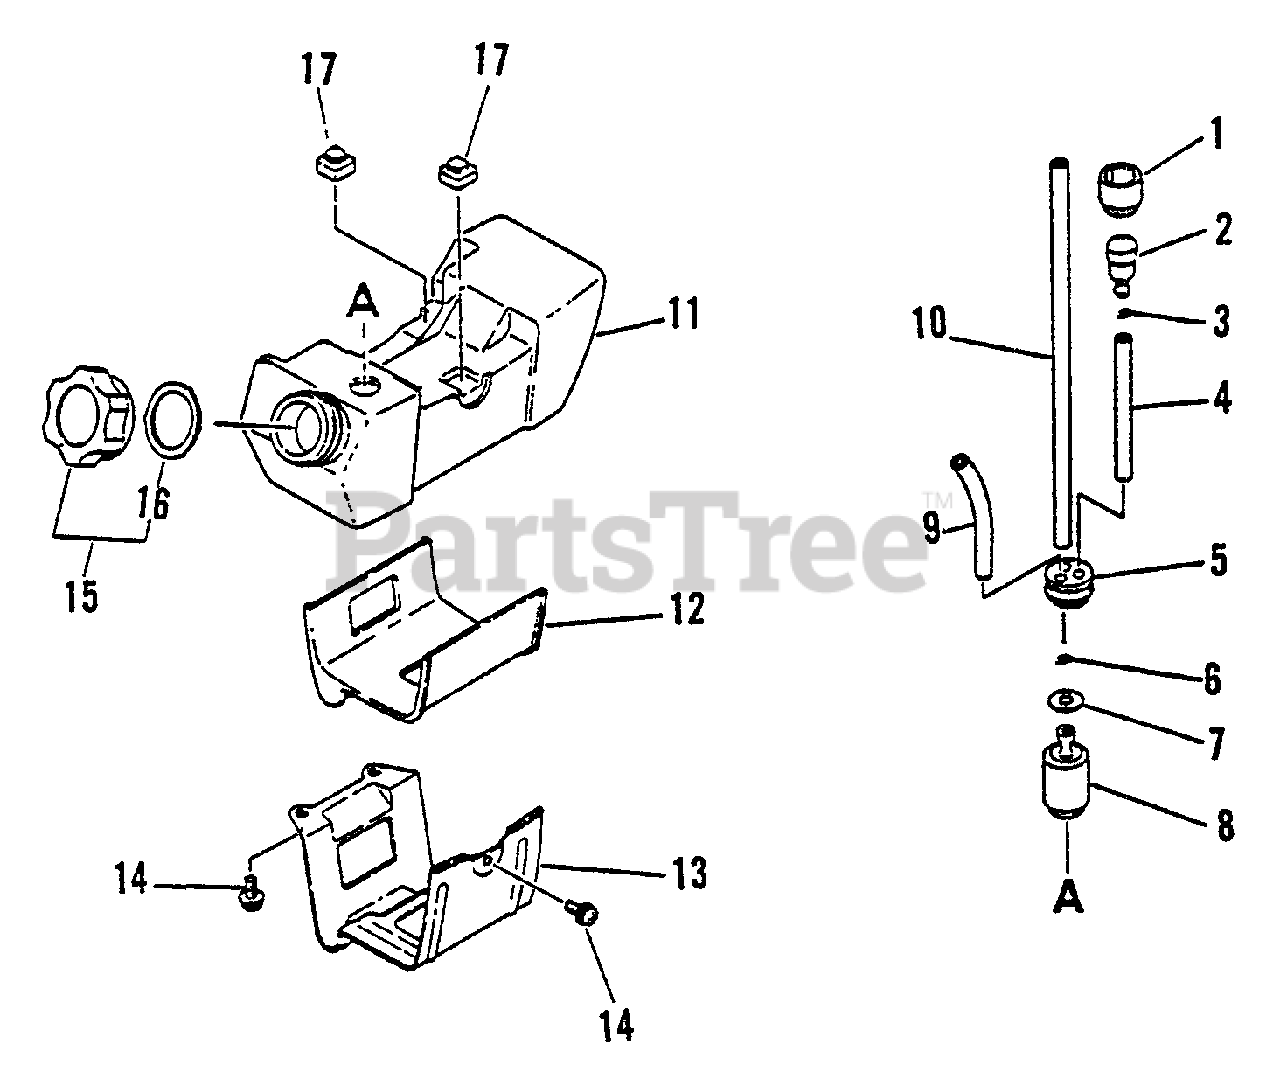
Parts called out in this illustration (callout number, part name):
1	COVER, VENT
2	VENT, FUEL TANK
3	CLIP - 6
4	PIPE - 3X6X70 -- BLACK
5	GROMMET
6	CLIP - 5.5
7	WASHER - 5
8	FILTER, FUEL
9	PIPE - 3X6X90 -- CLEAR
10	PIPE - 3X5X180 -- BLACK
11	TANK, FUEL
13	BRACKET, FUEL TANK
14	SCREW - 5X12
15	CAP ASSY
16	GASKET, CAP
17	CUSHION, FUEL TANK
